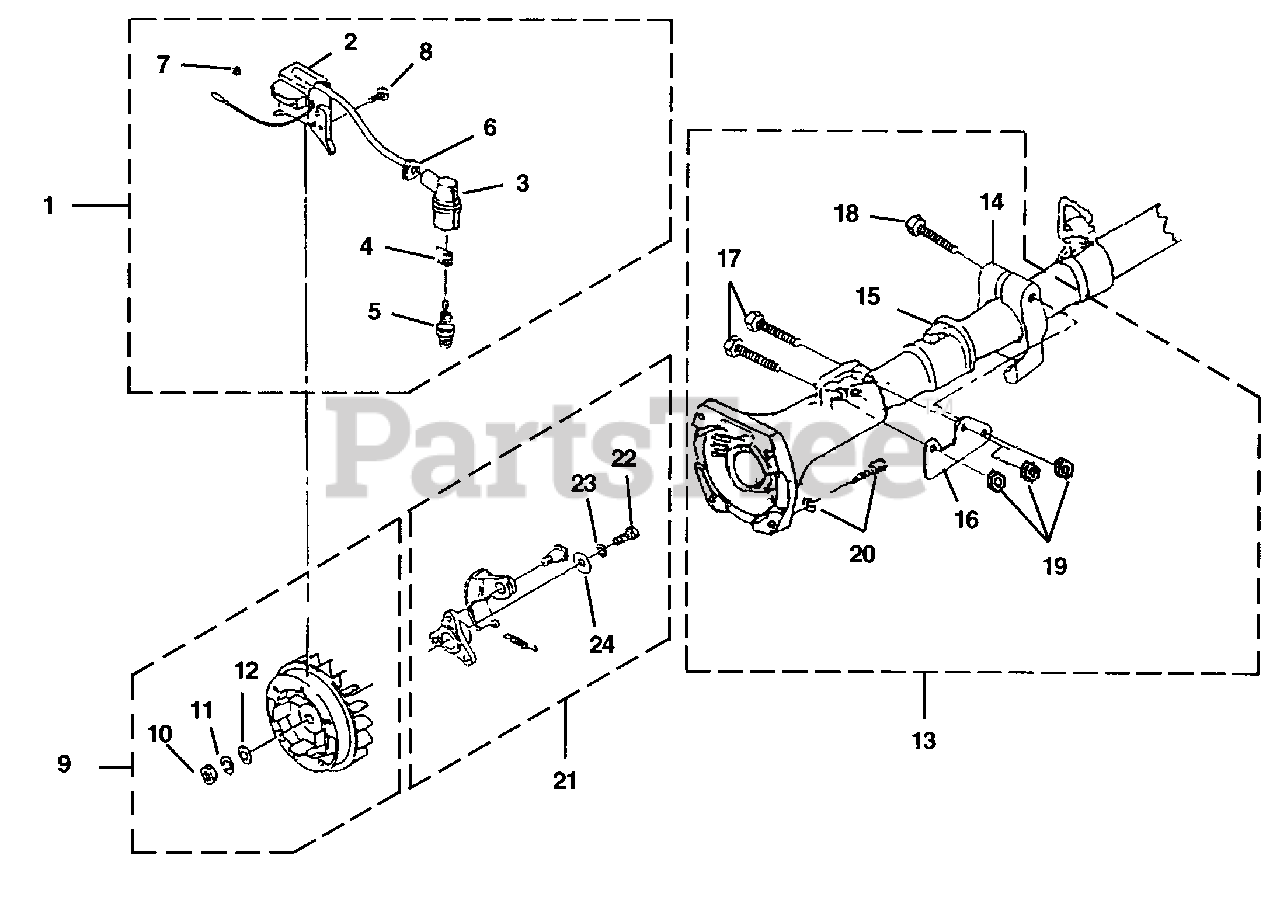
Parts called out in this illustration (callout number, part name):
1	IGNITION KIT
2	MODULE - Ignition
3	CAP, PLUG
5	SPARK PLUG
8	SCREW - Socket Hd (MS X 18W SW)
9	ROTOR ASSEMBLY
11	WASHER - Spring
13	CLUTCH HSG ASSY
17	BOLT (M6 X 30)
20	SCREW - Socket Hd (M6 X 18W SW)
21	CLUTCH ASSEMBLY
22	BOLT
23	WASHER - Spring
